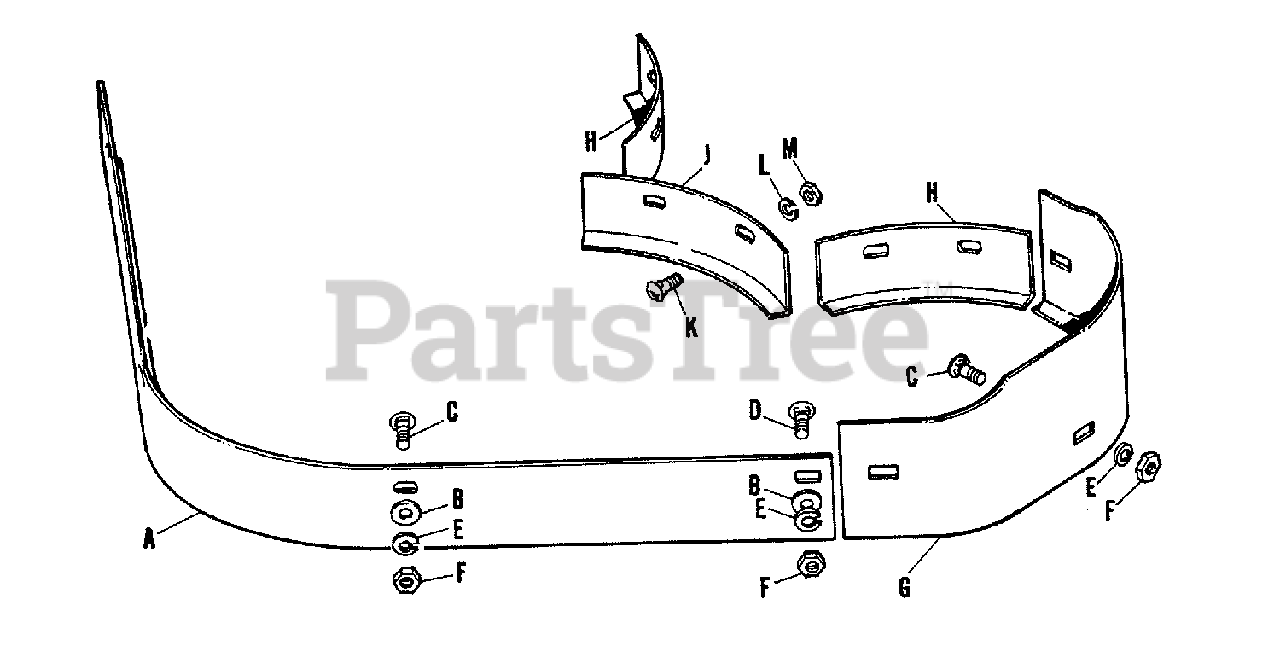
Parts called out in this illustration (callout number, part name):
A	FRONT BAFFLE, Mulcher
B	WASHER, Plain, 3/8"
C	CARRIAGE BOLT, 3/8"-16 x 3/4"
D	CARRIAGE BOLT, 3/8"-16 x 3/4"
E	WASHER, Lock, 3/8"
F	NUT, Hex, Full, 3/8"-16 NC
G	END PLATE, Housing
H	BAFFLE, Mulcher, Rear Side
J	BAFFLE, Mulcher, Rear Center
K	CARRIAGE BOLT, 5/16"-18 x 3/4"
L	WASHER, Lock, 5/16"
M	NUT, Hex, Full, 5/16"-18
